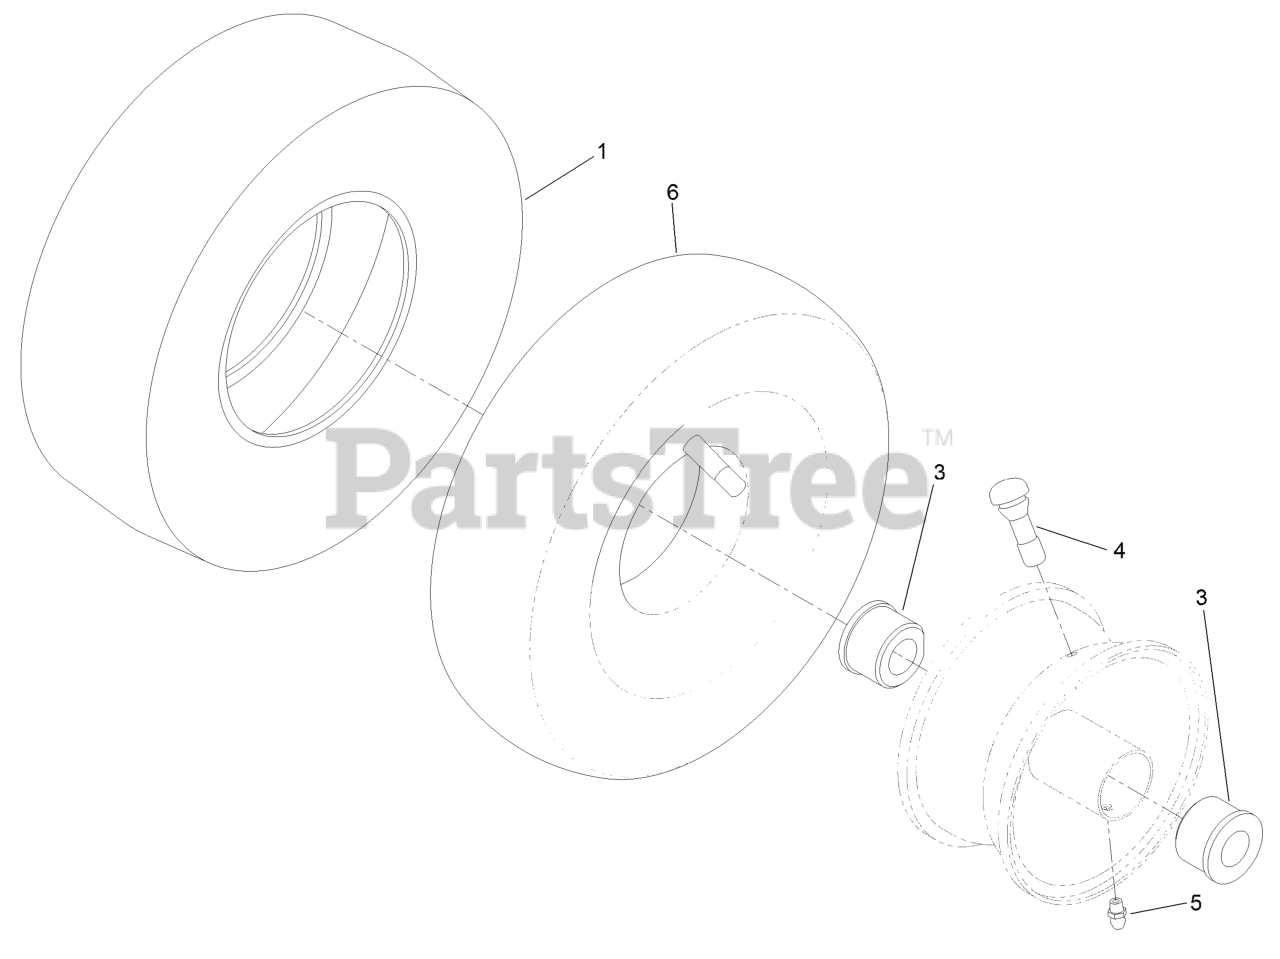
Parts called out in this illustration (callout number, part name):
3	BUSHING-FLANGE
4	Stem-Valve
5	FITTING-GREASE
6	TUBE-INNER
